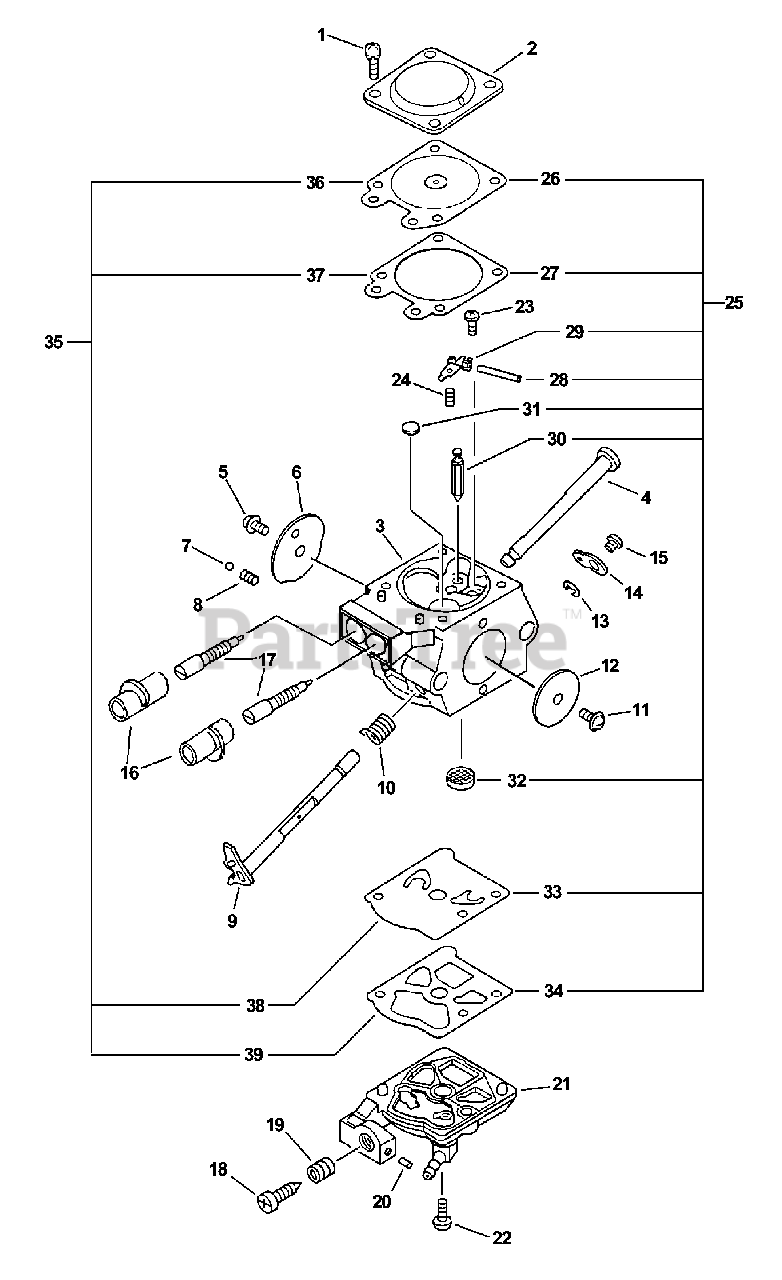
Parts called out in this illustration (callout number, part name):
1	SCREW
2	COVER, METERING
3	BODY, CARBURETOR
4	SHAFT, CHOKE
6	VALVE, CHOKE
7	BALL, CHOKE
9	SHAFT, THROTTLE
10	SPRING, THROTTLE RETURN
12	VALVE, THROTTLE
13	RING, RETAINING
14	LEVER, THROTTLE
16	CAP, LIMITER
17	NEEDLE - MIXTURE
18	SCREW, IDLE ADJUST
19	SPRING, IDLE ADJUST
21	COVER, PUMP
22	SCREW, PUMP COVER
23	SCREW, METERING LEVER PIN
24	SPRING, METERING LEVER
25	REPAIR KIT
26	DIAPHRAGM, METERING
27	GASKET, METERING
28	PIN, METERING LEVER
29	LEVER, METERING
30	VALVE, INLET NEEDLE
31	PLUG, WELCH
32	STRAINER
33	DIAPHRAGM, PUMP
34	GASKET, PUMP
35	DIAPHRAGM/GASKET KIT
36	DIAPHRAGM, METERING
37	GASKET, METERING
38	DIAPHRAGM, PUMP
39	GASKET, PUMP
